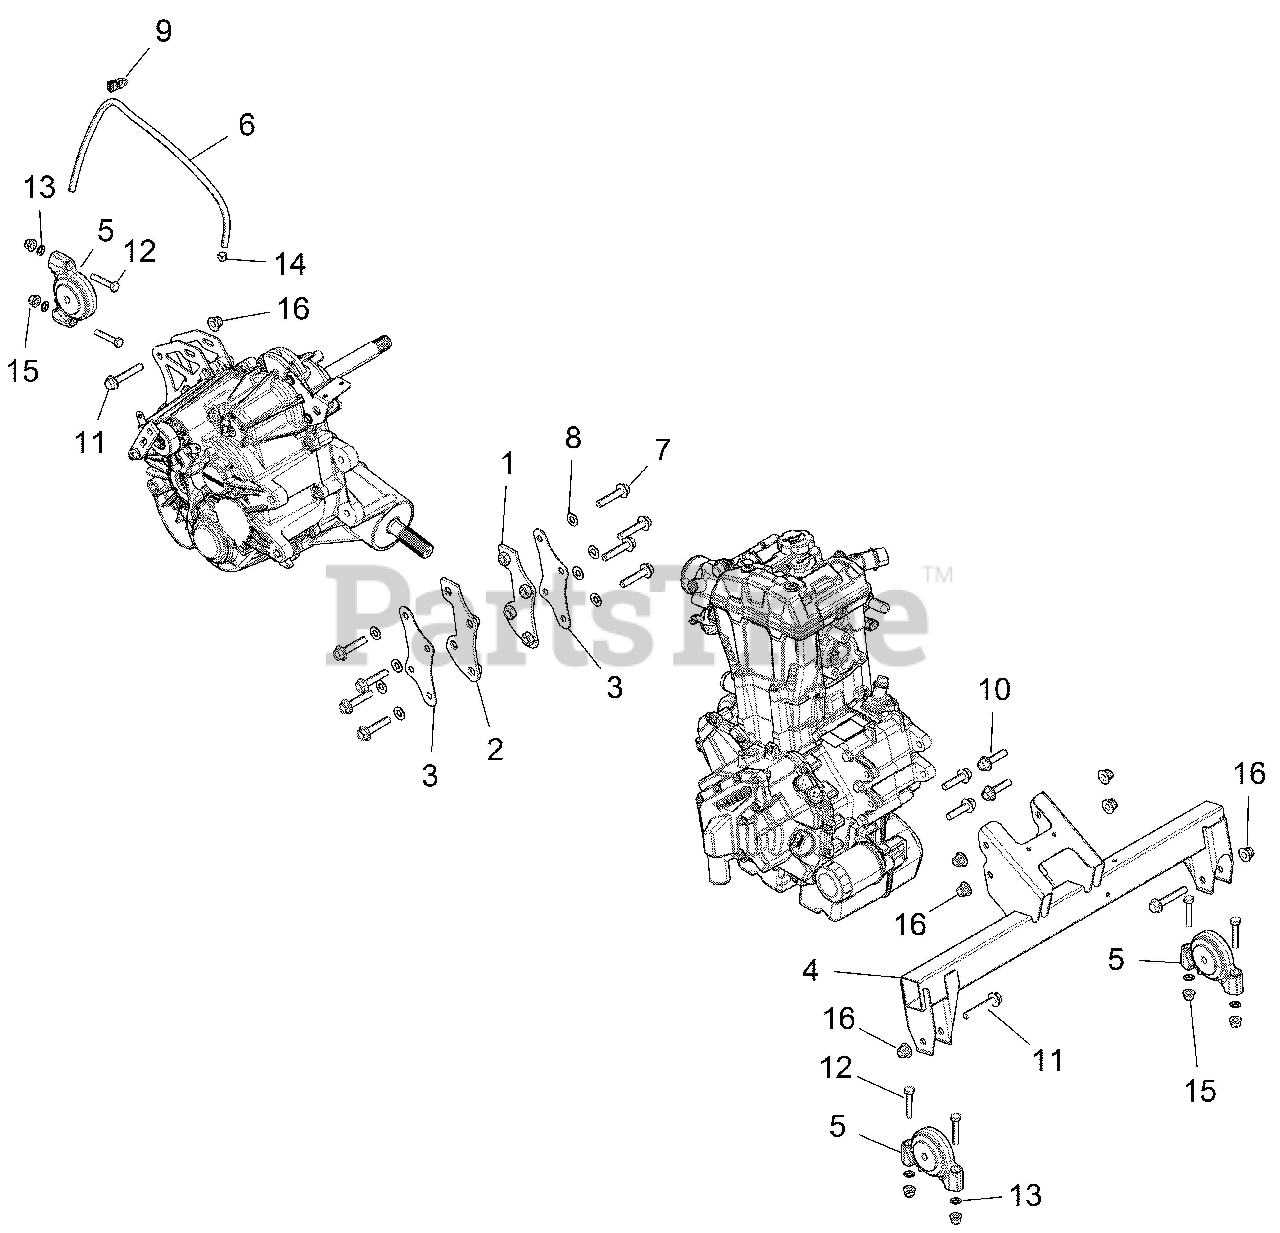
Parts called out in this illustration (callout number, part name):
1	WELD-TRANS,INNER,LEFT
2	WELD-TRANS,INNER,RIGHT
3	BRKT-COUPLER,TRANS,OUTER
4	WELD-MOUNT,ENGINE,BLK
5	MOUNT-ISOLATOR,DRIVELINE
6	LINE,FUEL,1/4 ID(1525 CM.)
7	SCR-M10X1.5X50 8.8 HX/FL ZOD
8	WASHER,3/8 FW
9	STRAP-CABLE TIE W/EDGE CLIP
10	SCR-HXFL-M10X1.25X40 8.8 ZOD
11	BOLT-M10X1.25X60,HXFLG-OLIVE D
12	SCR-HH M8X1.25X45 8.8 ZOD
14	CLAMP,HOSE(10)
15	NUT-M8X1.25,FLG,NYLOC-OLIVE D
16	NUT-M10X1.25,FLG,NYLOC-OLIVE D
